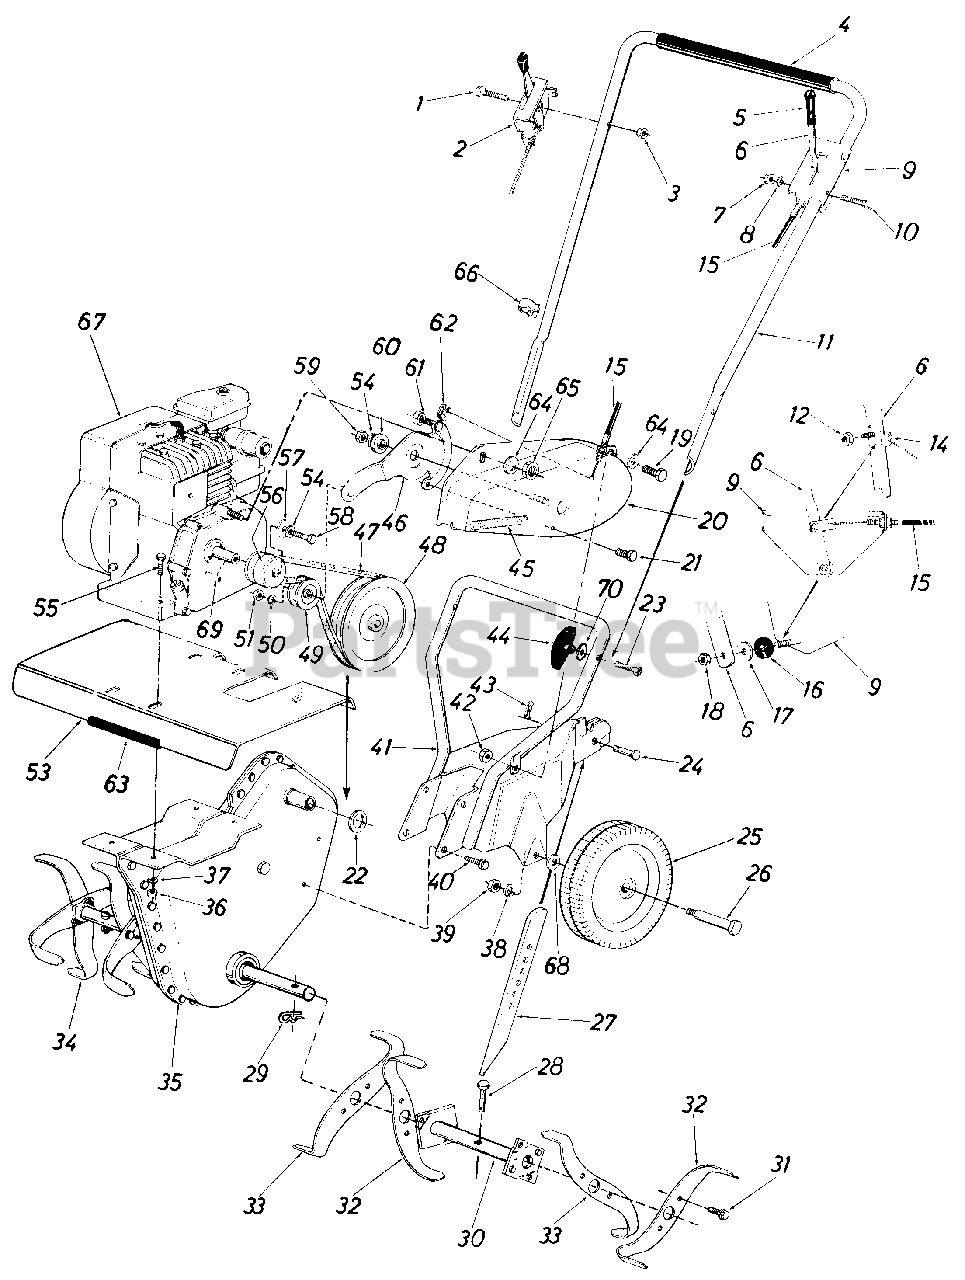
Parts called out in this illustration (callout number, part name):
1	Hex Bolt 1/4-20 x 1.50" Lg.
2	Throttle Control Ass'y. Comp.
3	Hex Cent. L-Nut 1/4-20 Thd.
4	Grip - 12" Lg.
5	Handle Grip
6	Clutch Handle Ass'y.
7	Hex Cent. L-Nut 1/4-20 Thd.
8	Fl-Wash. 1/4" I.D. x .50" O.D. x .063
9	Clutch Handle Brkt. Ass'y.
10	Carr. Bolt 1/4-20 x 1.25" Lg.
11	Upper Handle
12	Hex Cent. L-Nut 1/4-20 Thd.
15	Clutch Cable
16	Rubber Wash.
17	Fl-Wash. 1/4" I.D. x .75" O.D. x .063
18	Hex Cent. L-Nut 1/4-20 Thd.
19	Hex Bolt 1/4-20 x .50" Lg.
20	Belt Cover Ass'y.
21	Hex Wash. Hd. Tap Scr. 1/4 x .50"
22	Fl-Wash. .52 I.D. x 1.00 O.D. x .050
23	Curved Hd. Bolt 5/16-18 x 1.75" Lg.
24	Clevis Pin
25	Wheel Ass'y.
26	Shoulder Bolt
27	Depth Bar
28	Clevis Pin .31 Dia. x 1.50" Lg.
29	Hairpin Cotter
34	Tine Ass'y. Comp.
35	Chain Case Ass'y. Comp.
36	Hex Nut 5/16-18 Thd.
37	L-Wash. 5/16" Scr.
38	L-Wash. 3/8" Scr. H.D.
39	Hex Cent. L-Nut 3/8-16 Thd.
40	Hex Wash. SF-Tap Scr. 5.16 18 x .50" Lg.
43	Intern. Cotter Pin
44	Hand Knob
45	Extension Spring .60 O.D. x 4.88" Lg.
46	Idler Arm Ass'y.
47	Belt 3/8" x 29" Lg.
48	Chain Case Pulley 5 1/2 x 1/2"
49	Fl-Idler 2"
50	L-Wash. 5/16" Scr.
51	Hex Nut 3/8-24 Thd.
55	Hex Bolt 5/16-18 x 1.50" Lg.
56	Engine Pulley 3/8 V x .7525 I.D. x 2" O.D.
57	Fl-Wash. .385 I.D. x 1.00" O.D. x .135
58	Hex Bolt 3/8-24 x 1.00" Lg.
59	Hex Nut 5/16-18 Thd.
60	Shld. Spacer .50" Dia. x .133
61	Hex Cent. L-Nut 1/4-20 Thd.
63	Trim Strip - 4"
64	Fl-Wash. .281" I.D. x .500" O.D. x .063
65	Hex Cent. L-Nut 1/4-20 Thd.
66	Cable Clip
67	Engine
68	Bell-Wash.
69	Square Key 3/16 x 3/4" Lg.
70	Belleville Washer
